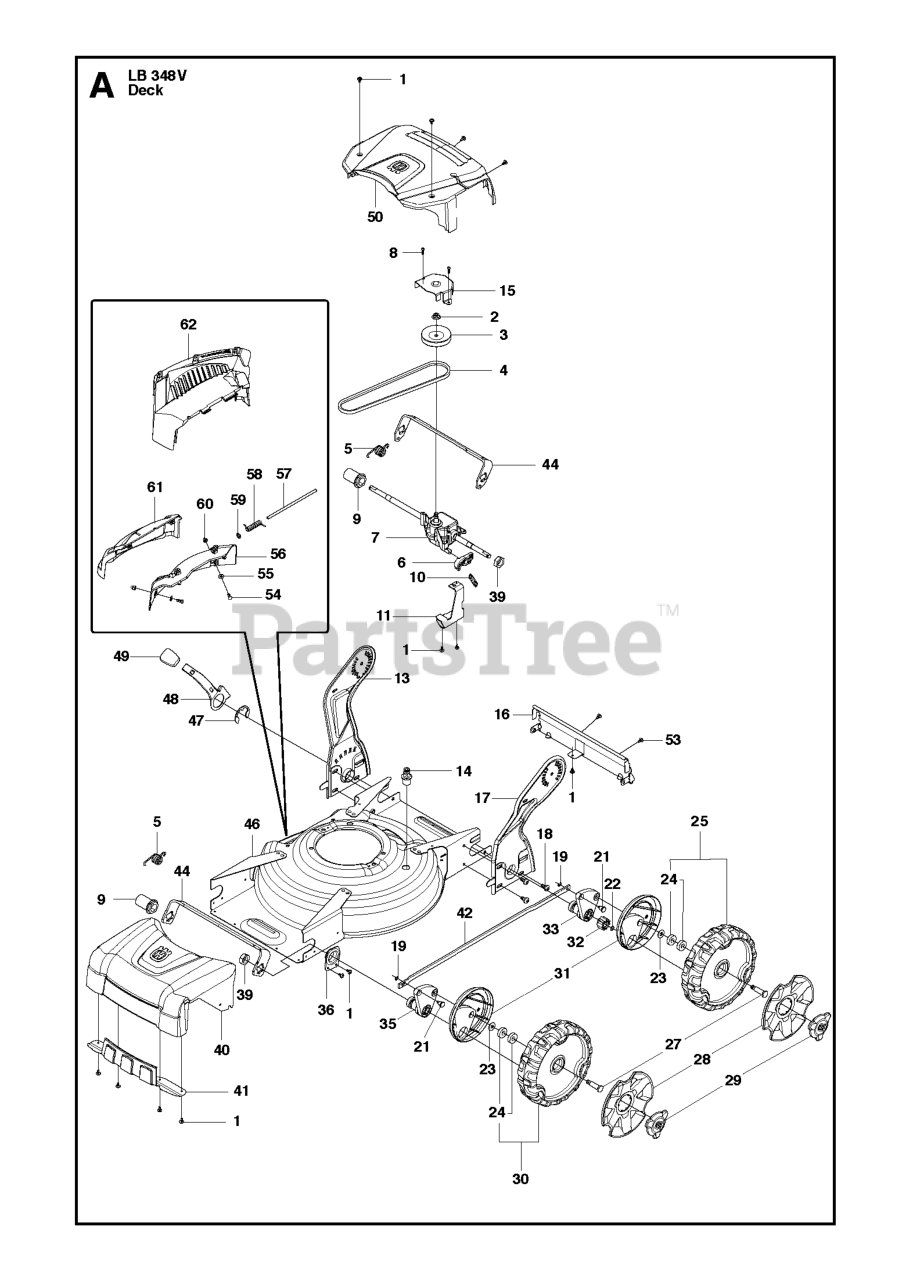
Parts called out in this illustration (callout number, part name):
1	SCREW ITXPANTT M5X10 ZPB (A00
4	BELT WRAPPED V-BELT Z 29.5
8	SCREW ITXPANT T50X16 ZN/FE (A
19	FASTENER
24	BALL BEARING
30	WHEEL ASSY 210, IDLE, MEDIUM
50	REAR COVER A009-2
53	SCREW ITXPANTT M5X10 ZPB (A00
